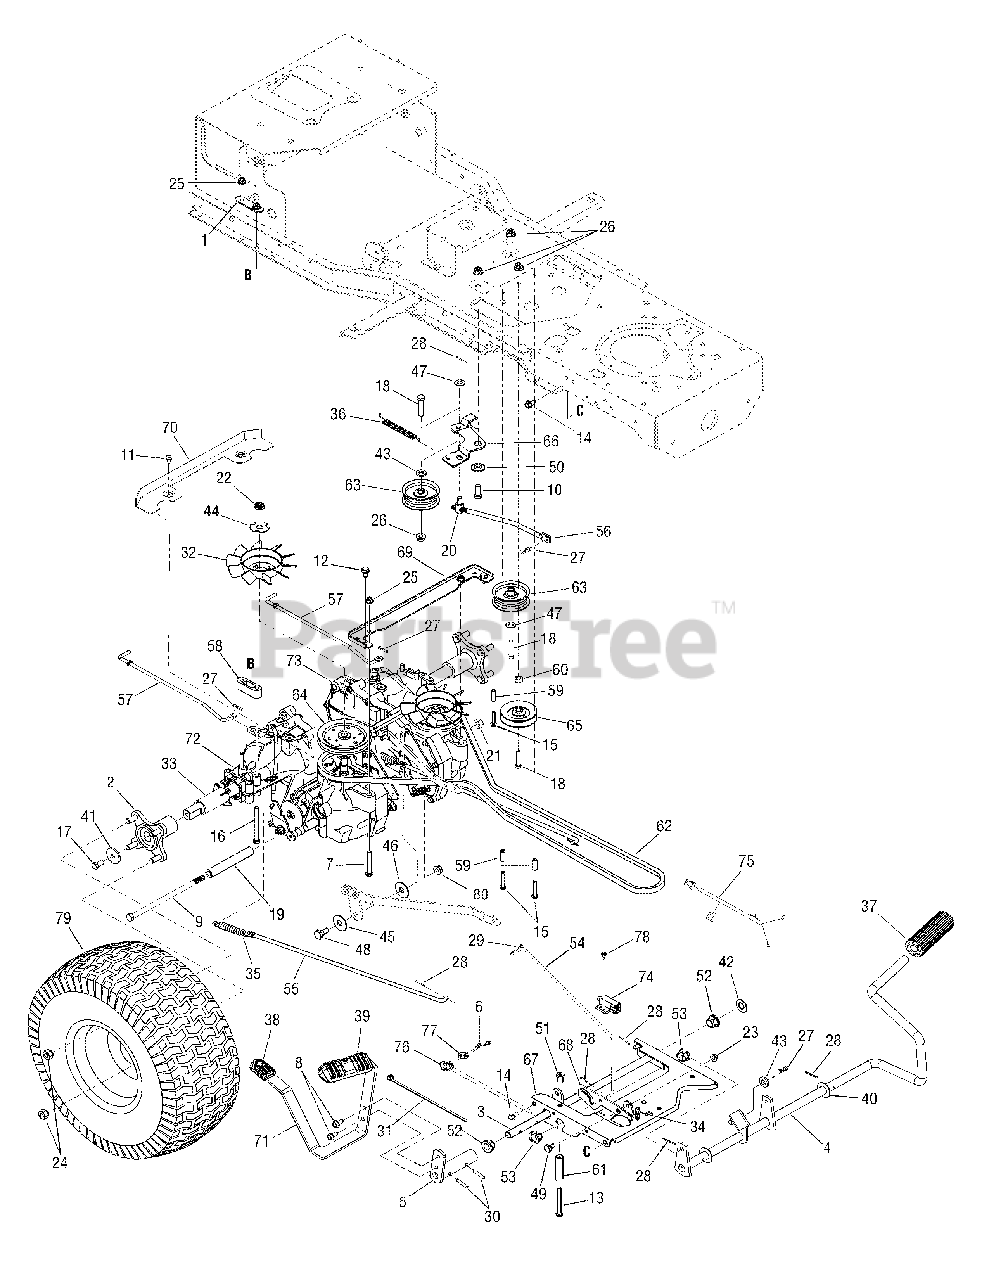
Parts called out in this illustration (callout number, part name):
2	Hub, Wheel
3	Shaft Assembly, Hydro Control Pedal
4	Shaft Assembly, Brake Control
7	Screw, Hex Cap, 5/16-18 x 2.25 Gr5
8	Screw, Hex Wash Hd. Tapp, 5/16-12 x .75
9	Screw, Hex Cap, 7/16-14 x 8.5 Gr5
10	Screw, Hex Cap, 3/8-16 x 1.0 Gr5
11	Screw, Hex Wash. Hd. Tapp, 1/4-20 x .5
12	Screw, Hex Wash Hd. Tapp, 5/16-18 x .5
13	Screw, Hex Cap, 1/4-20 x 2.25 Gr5
14	Screw, Hex Wash Hd. Tapp, 5/16-12 x .75
15	Screw, Hex Wash Hd. Tapp, 1/4-20 x .75
16	Screw, Hex Cap, 5/16-18 x 3.5 Gr5
17	Screw, Hex Cap Lock, 3/8-16 x .75 Gr5
18	Screw, Hex Cap, 3/8-16 x 2.0 Gr5
19	Spacer, .479 x .75 x 4.97
20	Ferrule, 3/8-24 x .375 Dia.
21	Nut, Hex Lock, 7/16-14 GrA
22	Nut, Hex Jam Insert Lock, 1/2-20 Gr5
23	Nut, Hex Flange Lock, 5/16-18 Gr5
24	Nut, Lug, 7/16-14
25	Nut, Hex Flange Insert Lock, 5/16-18 GrF
26	Nut, Hex Flange Insert Lock, 3/8-16 GrF
27	Pin, Internal Cotter
28	Pin, Cotter, 3/32 x 1/0
29	Pin, Bowtie Cotter
30	Pin, Spirol, .25 x 1.25
31	Tie, Cable
32	Fan, Hydro
33	Sleeve, 1.015 x 2.6
34	Spring, Compression, .405 x 1.17
35	Spring, Extension, .59 x 4.0
36	Spring, Extension, .56 x 5.52
37	Pad, Foot, 4.0 in. Lg
38	Pad, Reverse Pedal
39	Pad, Forward Pedal
40	Washer, Flat, .64 x 1.24 x .06 HT
41	Washer, Flat, .39 x 1.5 x .134
42	Washer, Flat, .625 x 1.0 x .067 HT
43	Washer, Flat, .407 x .812 x .135 HT
44	Washer, Hydro Lock
45	Washer, Flat, .531 x 1.75 x .09
46	Washer, Flat, .406 x 1.5 x .105
47	Washer, Flat, .406 x .812 x .051
48	Bolt, Shoulder, .496 x .336: 3/8-16
49	Bolt, Shoulder, .435 x .160 : 5/16-18
50	Spacer, Shoulder, .625 ID x .169
51	Nut, Shoulder, .375 Dia x .5
52	Bearing, Hex Flange
53	Bearing, Hex Flange, .625 ID Split
54	Rod, Park Brake
56	Rod, Drive Engage
57	Rod, Hydro Bypass
58	Spacer, T-Axle
59	Spacer, .26 x .372 x 1.42
60	Spacer, .38 x .625 x .265
61	Spacer, .375 x .5 x 2.0
62	V-Belt, 88.4
63	Pulley, Flat Idler, 2.75
64	Pulley, V Type, 4.5
65	Pulley, V Type Idler, 3.06
71	Pedal, Hydro Drive
72	Transmission, Hydro RH
73	Transmission, Hydro LH
74	Switch, Interlock (Brake)
75	Harness, Reverse Jumper
76	Switch, Reverse
77	Plate, Insulator Nut
78	Screw, Shoulder, #10-32 : .5
79	Valve, Tubeless Air
80	Nut, Hex Lock, 3/8-16
